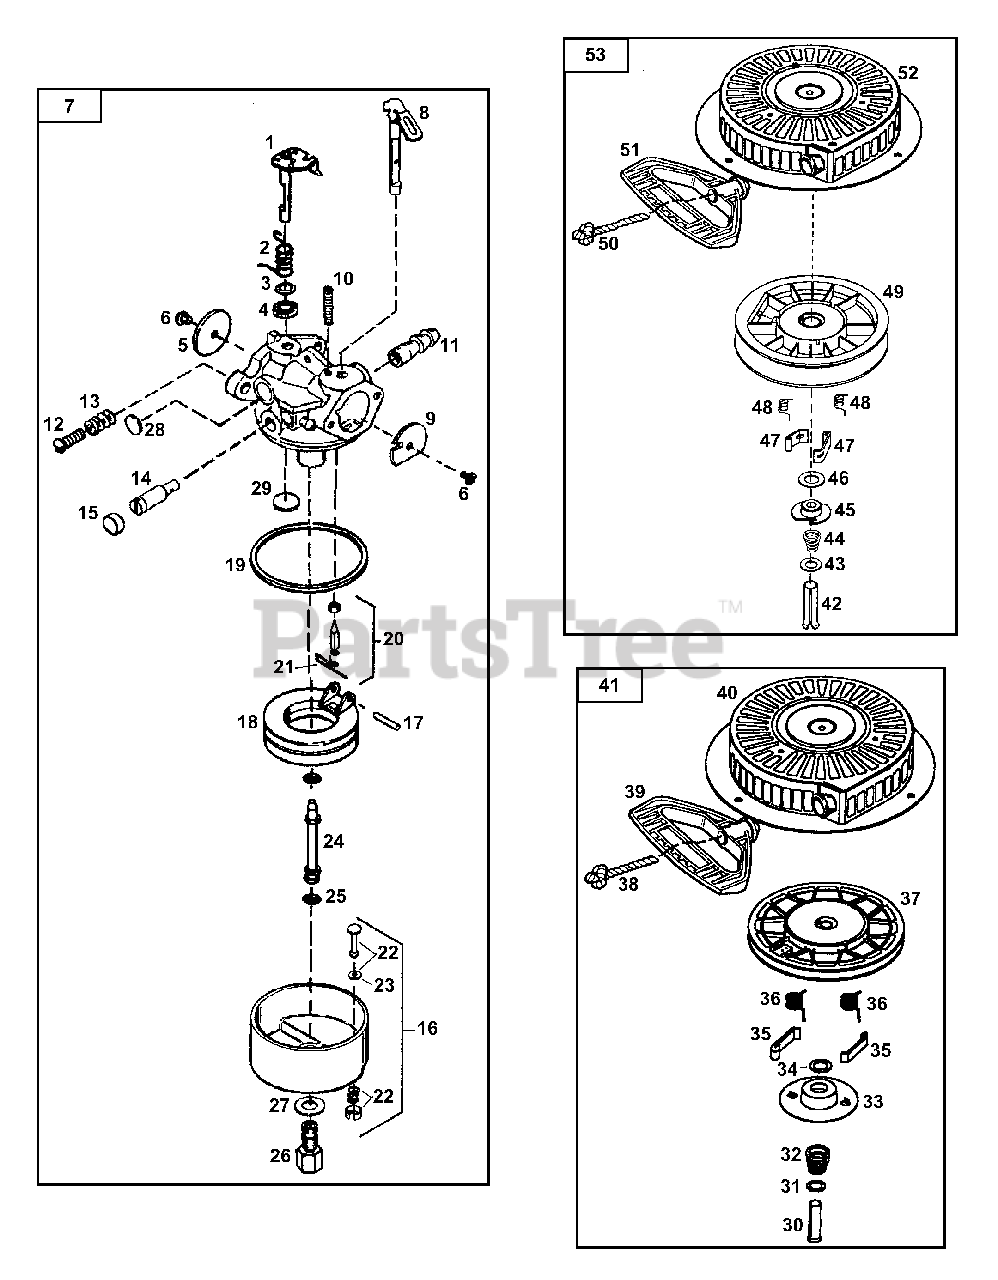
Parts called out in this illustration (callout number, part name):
1	Throttle Shaft & Lever Ass'y
2	Throttle Return Spring
3	Dust Seal Washer
4	Dust Seal (Throttle)
5	Throttle Shutter
6	Shutter Screw
7	Carburetor Ass'y
8	Choke Shaft & Lever Ass'y
9	Choke Shutter
10	Choke Positioning Spring
11	Fuel Fitting
12	Throttle Crack/Idle Speed Screw
13	Tension Spring
14	Idle Restrictor Screw
15	Idle Restrictor Screw Cap
16	Float Bowl
17	Float Shaft
18	Float
19	Float Bowl "O" Ring
20	Inlet Needle, Seat & Clip
21	Spring Clip
22	Bowl Drain Ass'y
23	Drain Plunger Gasket
24	Main Nozzle Tube
25	Main Nozzle Tube "O" Ring
26	High Speed Bowl Nut
27	Bowl Nut Washer
28	Welch Plug, Idle Mixture Well
29	Welch Plug, Atmospheric Vent
30	Spring Pin,
32	Brake Spring
35	Starter Dog
36	Dog Spring
37	Pulley & Rewind Spring Ass'y
38	Starter Rope (98")
39	Mitten Grip Starter Handle
40	Starter Housing Ass'y
41	Rewind Starter Ass'y
42	Spring Pin,
44	Brake Spring
47	Starter Dog
48	Dog Spring
49	Pulley & Rewind Spring Ass'y
50	Starter Rope (98")
51	Mitten Grip Starter Handle
52	Starter Housing Ass'y
53	Rewind Starter Ass'y
